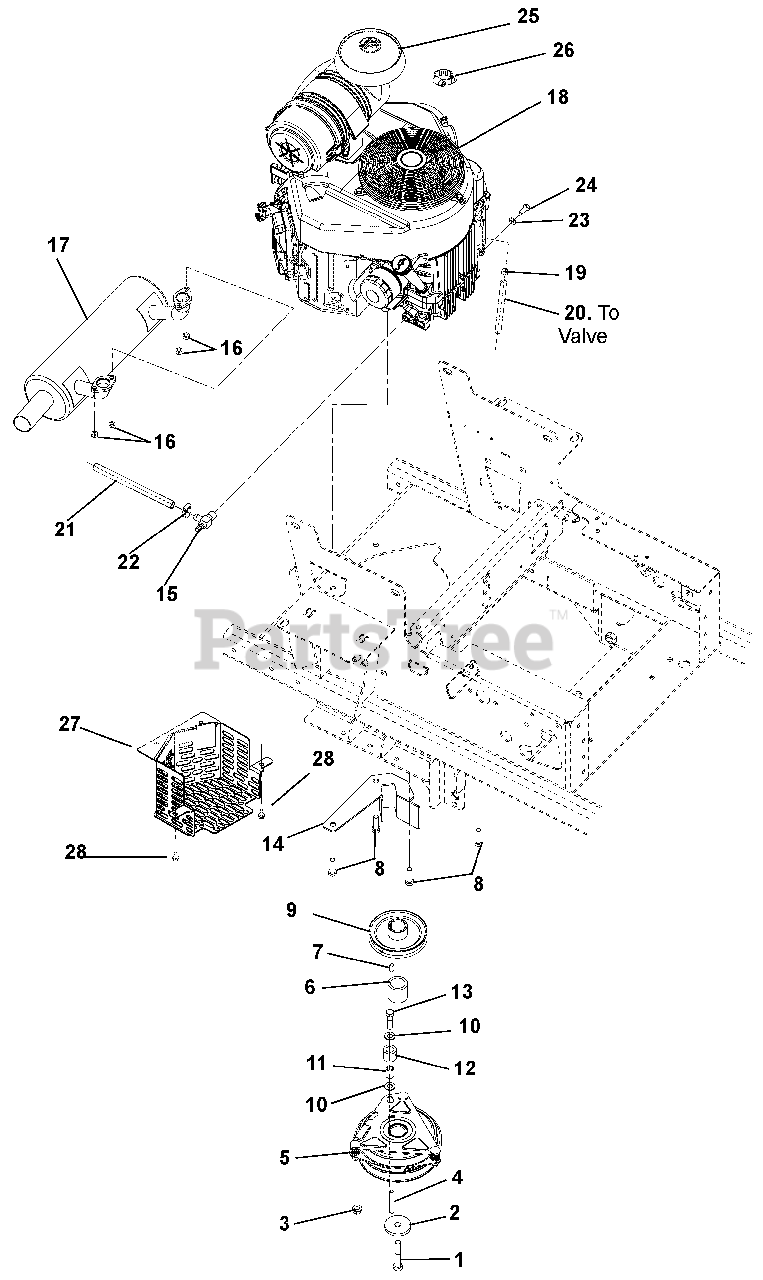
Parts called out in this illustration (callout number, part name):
1	Bolt, Hex .44-20 x 2.50
2	Washer, Flat-Steel .469 x 2.00 x .25
3	Nut, Locking-Top-Flange .38-16
4	Key .25 x .25 x 2.25
5	Clutch, Ogura GT2.5-FE02
6	Spacer, 1.125 x 1.50 x 1.40
7	Key, Square .25 x .625 x .25 SAE 8630 or SAE 1035
8	Bolt, Hex .38-16 x 1.25 FTH EP80
9	Pulley, 4.50 OD x 1.127 Engine
10	Washer, Flat-Steel .406 x .812 x .065
11	Bushing, Sleeve .407 x .625 x .813 Steel
12	Bumper, Rubber .62 x 1.0 x .88 LG Engine
13	Bolt, Hex .38-16 x 1.50
14	100I Clutch Stop Weldment
15	Drain, .50 Oil
16	Nut, Locking-Top M8-1.25
17	Muffler, Kawasaki Fixed
18	Engine, Kawasaki FX691
19	Clamp, Fuel Line
20	Hose, .25 Low-PERM Bulk Gas
21	Tube, Oil Drain 8" Clear Vinyl
22	Clamp, .88 Diameter Hose
23	Washer, Locking .31 x .078 Regular
24	Bolt, Hex M8-1.25 x 20
25	Cap, Air Cleaner Rain
26	Clamp, Hose 2.75 Dia. Worm
27	Weldment, Clutch and Belt Guard
28	Screw, Tapping .38-16 x .50 Hex Washer Head
